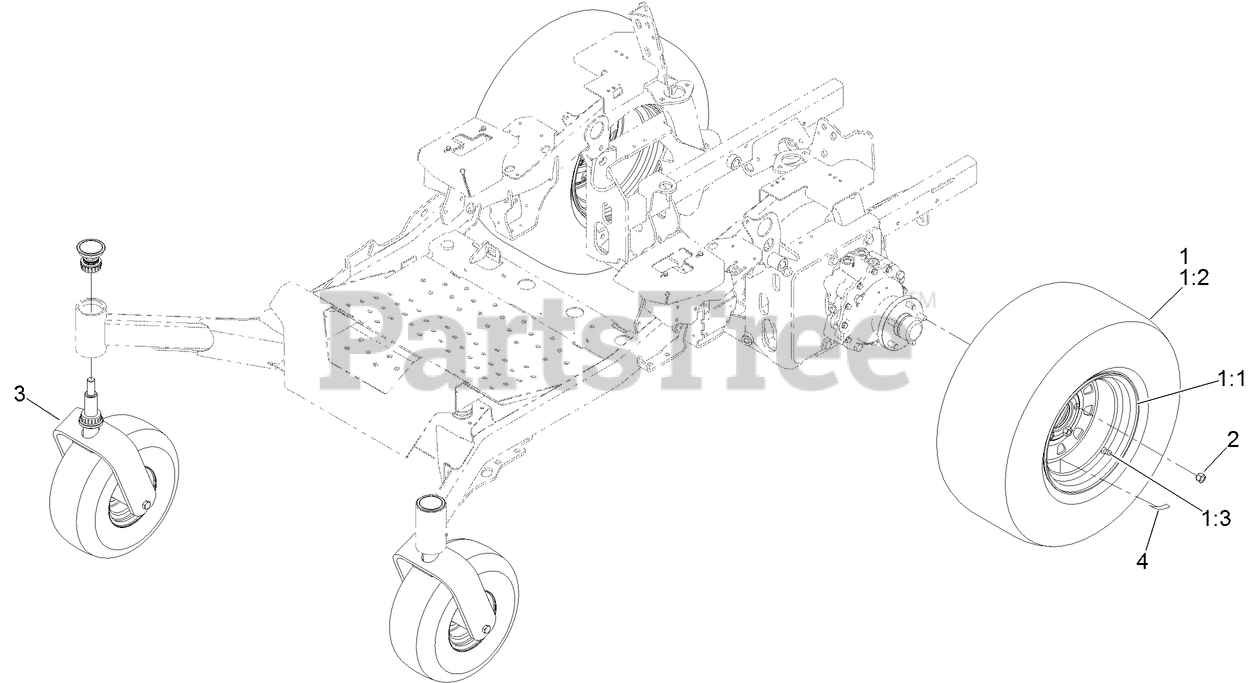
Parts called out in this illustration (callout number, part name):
1	TIRE ASM
2	NUT-LUG
3	CASTER WHEEL ASM
4	DECAL-TORQUE, WHEEL NUT
